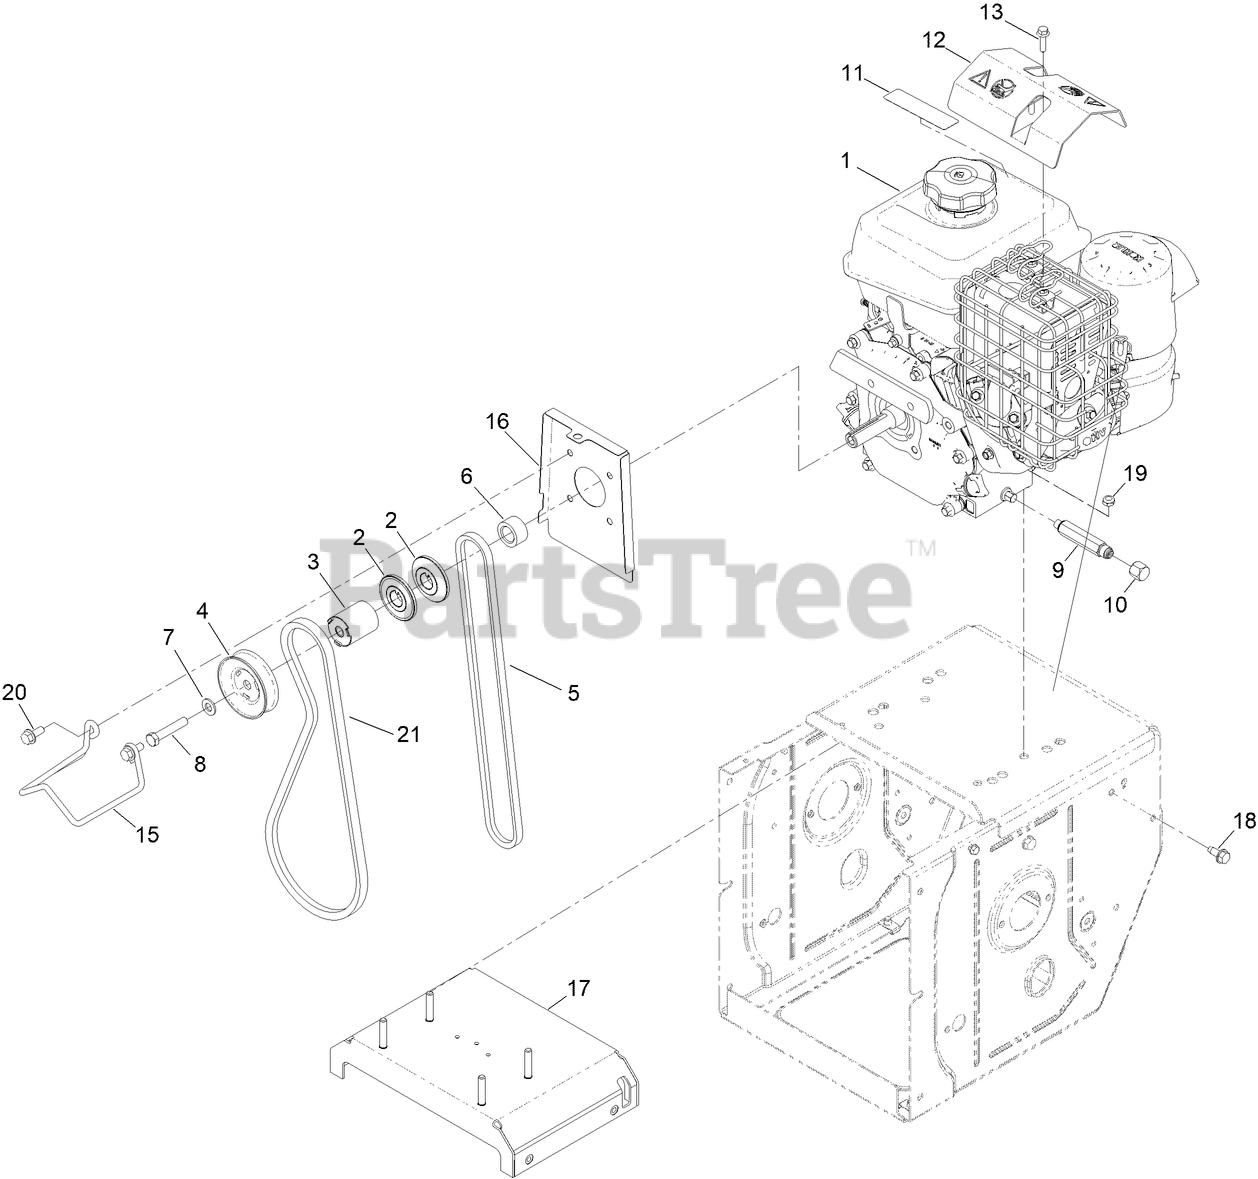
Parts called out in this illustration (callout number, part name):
2	SHEAVE-TRACTION
3	SPACER-PULLEY
4	PULLEY-IMPELLER
5	BELT,3L P21 DRIVE
6	SPACER
7	WASHER-FLAT
8	SCREW-HH
9	ADAPTER
11	DECAL-ARRESTOR, SPARK
12	DEFLECTOR,DEBRIS MUFFLER
13	SCREW-HHF
15	GUIDE-BELT
16	COVER-CRANK
17	PLATE-ENGINE, ASM
18	SCREW-HWHTF
19	NUT-HEX
20	SCREW-HH
21	V-BELT
